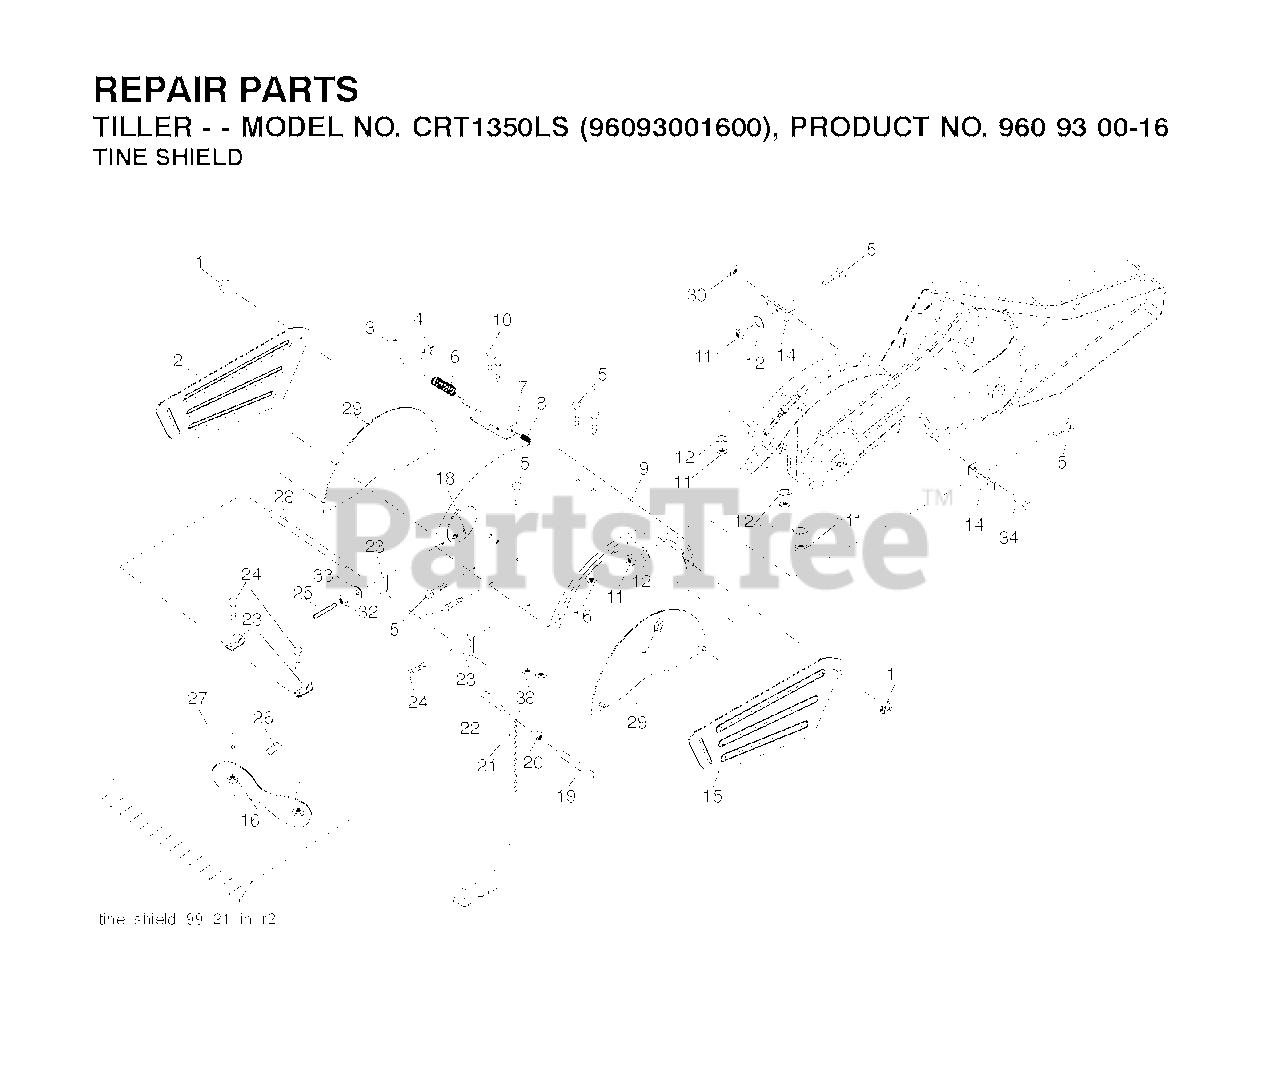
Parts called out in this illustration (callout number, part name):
1	NUT LOCK HEX FLANGE 5/16-18
2	SHIELD.SIDE.OUTER.LH.ORANGE
3	STAKE PIN TI
4	RING, KLIP
5	BOLT, RDHD SQNK 5/16-18 X 3/4
7	BRACKET.LATCH.STAKE.3.20.BLACK
8	SPRING CRT
9	SHIELD.TINE.TILLER.ORANGE
12	LOCKWASHER
14	BRACKET.TINE.SHIELD.TILLER
15	SHIELD.SIDE.OUTER.RH.ORANGE
16	NUT T
20	NUT.HEX.3/8-16UNC
21	STAKE.ASM.DEPTH
22	BOLT.375-16
25	VINYL CAP TI
26	PAD IDLER TI
27	SHIELD.PNT.LEVELING.ORANGE.668
28	PIN, HINGE
29	SHIELD.ASM.PNT.SIDE.ORANGE.668
30	LOCKNUT-FLANGE 5/16-18
32	NUT
33	LOCKWASHER
38	NUT
